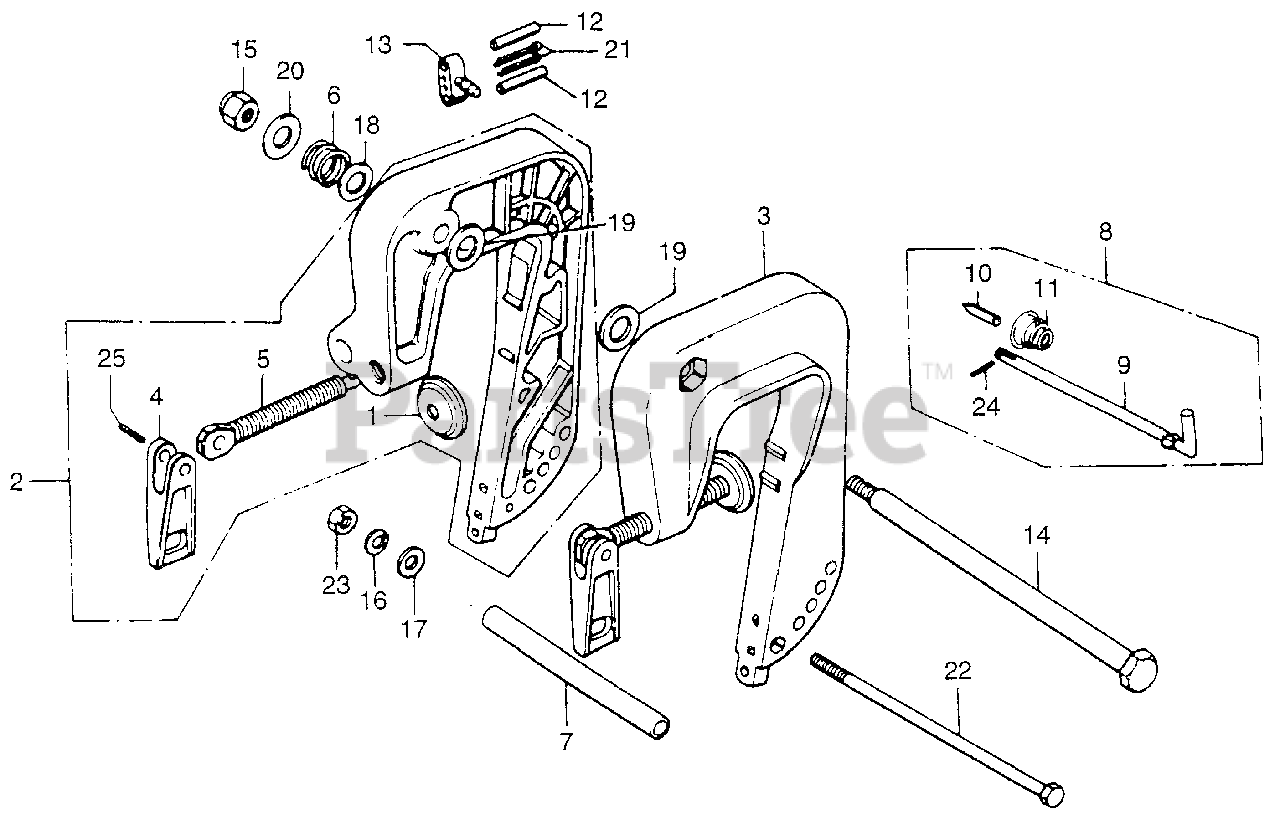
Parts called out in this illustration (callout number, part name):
1	PLATE, PUSH
2	BRACKET, R. STERN *B9* (ATLANTIS BLUE)
3	BRACKET, L. STERN *B9* (ATLANTIS BLUE) (NOT AVAILABLE)
4	GRIP, CLAMP *B9* (ATLANTIS BLUE)
5	SCREW, CLAMP
6	SPRING, TILT
7	COLLAR, DISTANCE (6MM)
8	ROD, ADJUSTING (N/A: SEE COMPONENTS)
9	ROD, ADJUSTING (NOT AVAILABLE)
10	STOPPER, ROD
11	SPRING, ADJUSTING ROD
12	PIN, SHEAR
13	HOLDER, PARTS
14	BOLT, TILTING
15	NUT, SELF-LOCK (8MM)
16	WASHER, SPRING (6MM)
17	WASHER, PLAIN (6MM)
18	WASHER, PLAIN (10MM)
19	WASHER (10MM)
20	WASHER (8MM)
21	PIN, COTTER (3MM)
22	BOLT, HEX. (6X160)
23	NUT, HEX. (6MM)
24	PIN, SPRING (2X8)
25	PIN, SPRING (4X14)
